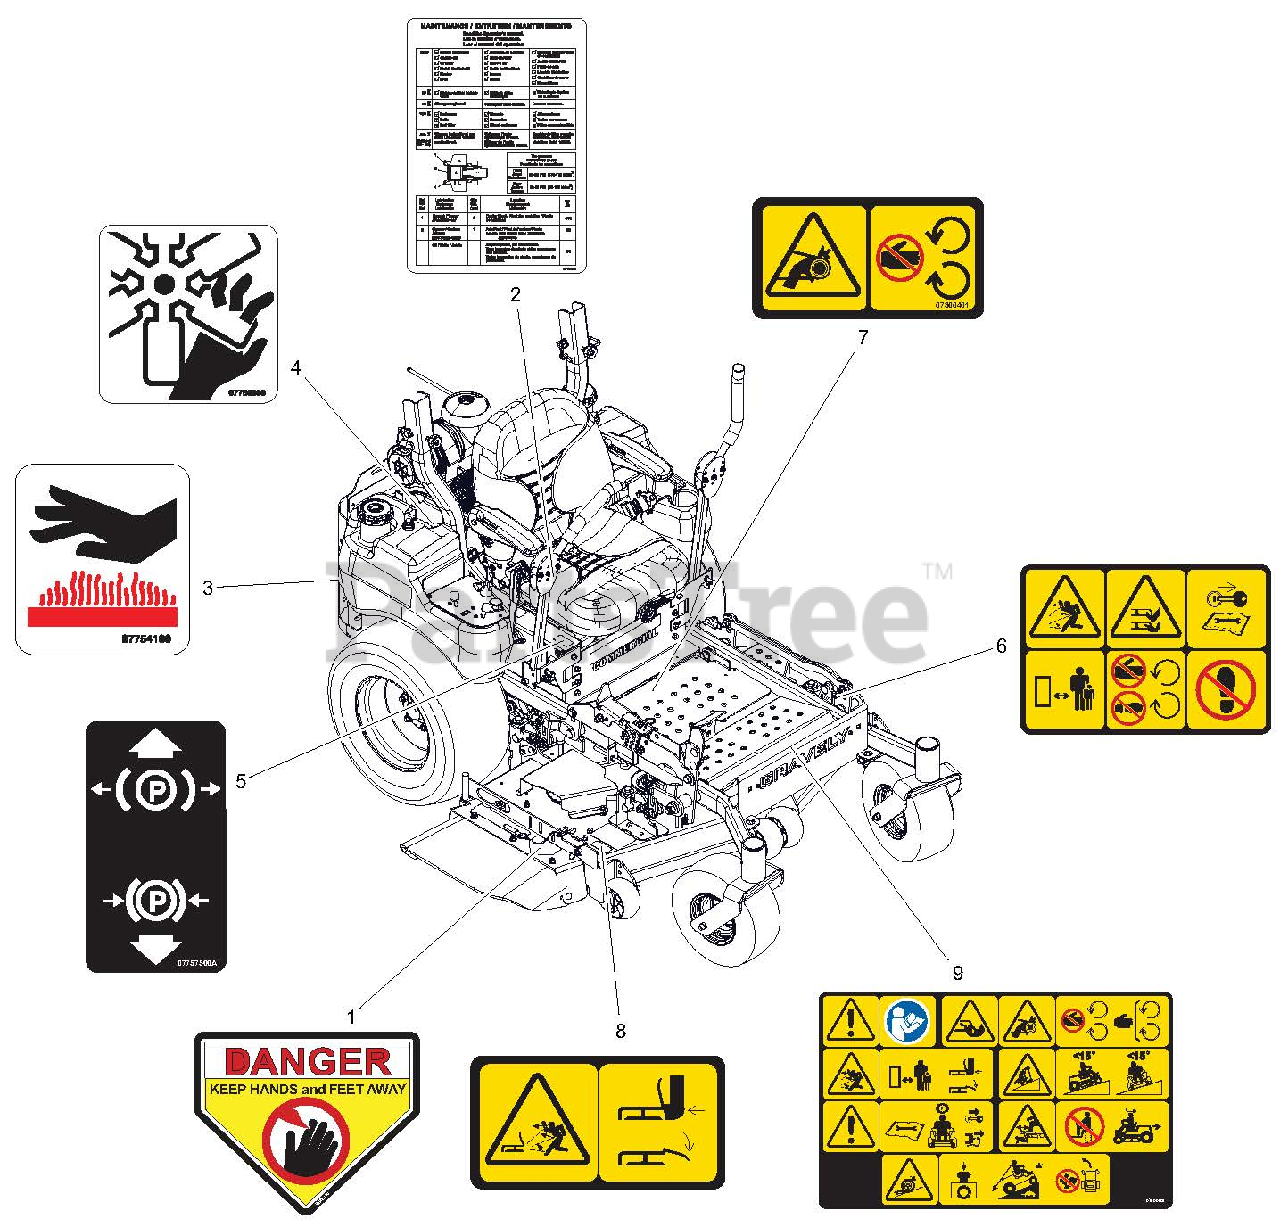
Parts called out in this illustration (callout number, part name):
1	DECAL, DANGER
2	DECAL, MAINTENANCE
3	DECAL HOT SURFACE
4	DECAL, DANGER - FAN
5	DECAL, PARKING BRAKE LEVER
6	DECAL, SAFETY - MOWER DECK
7	DECAL, SAFETY - GUARDING
8	DECAL, SAFETY - DECK GUARDING
9	DECAL, MAIN SAFETY, COMMERCIAL
